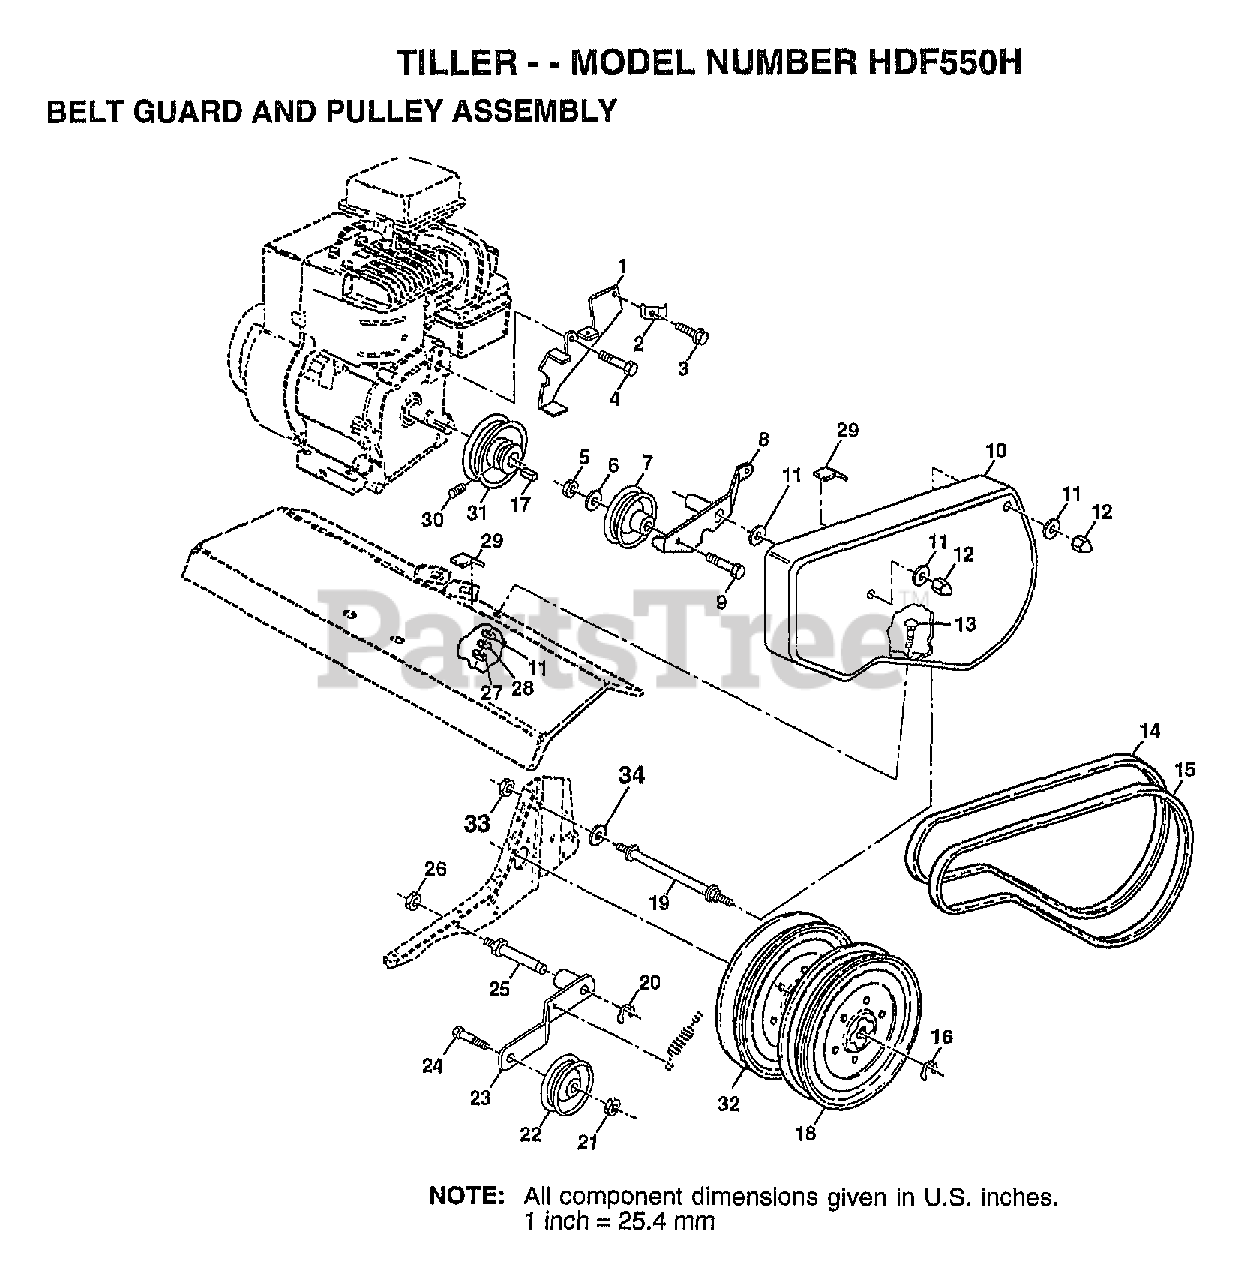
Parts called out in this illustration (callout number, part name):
1	ASSY.BRKT.BELT GUARD
2	CONDIUT CLIP T
4	BOLT.HEX.HEAD
5	NUT.HEX.3/8-16UNC
6	WASHER
7	PULLEY W/SPACER
8	ARM.ASM.REV.IDLER
10	GUARD.PNT.BELT.MS-428
11	WASHER
12	NUT-CAP TI
13	BOLT T
14	BELT-V
17	KEY T
18	"SHEAVE,TRANS.""D"""
19	BOLT TI
20	KLIP RING TI
21	NUT
22	"PULLEY,IDLER"
23	"ARM, IDLER"
25	SHAFT IDLER TI
26	JAM NUT TI
28	LOCKWASHER
29	PAD IDLER TI
30	SET SCREW
31	ENGINE PULLEY TI
32	SHEAVE.TRANS
33	NUT
34	WASHER
